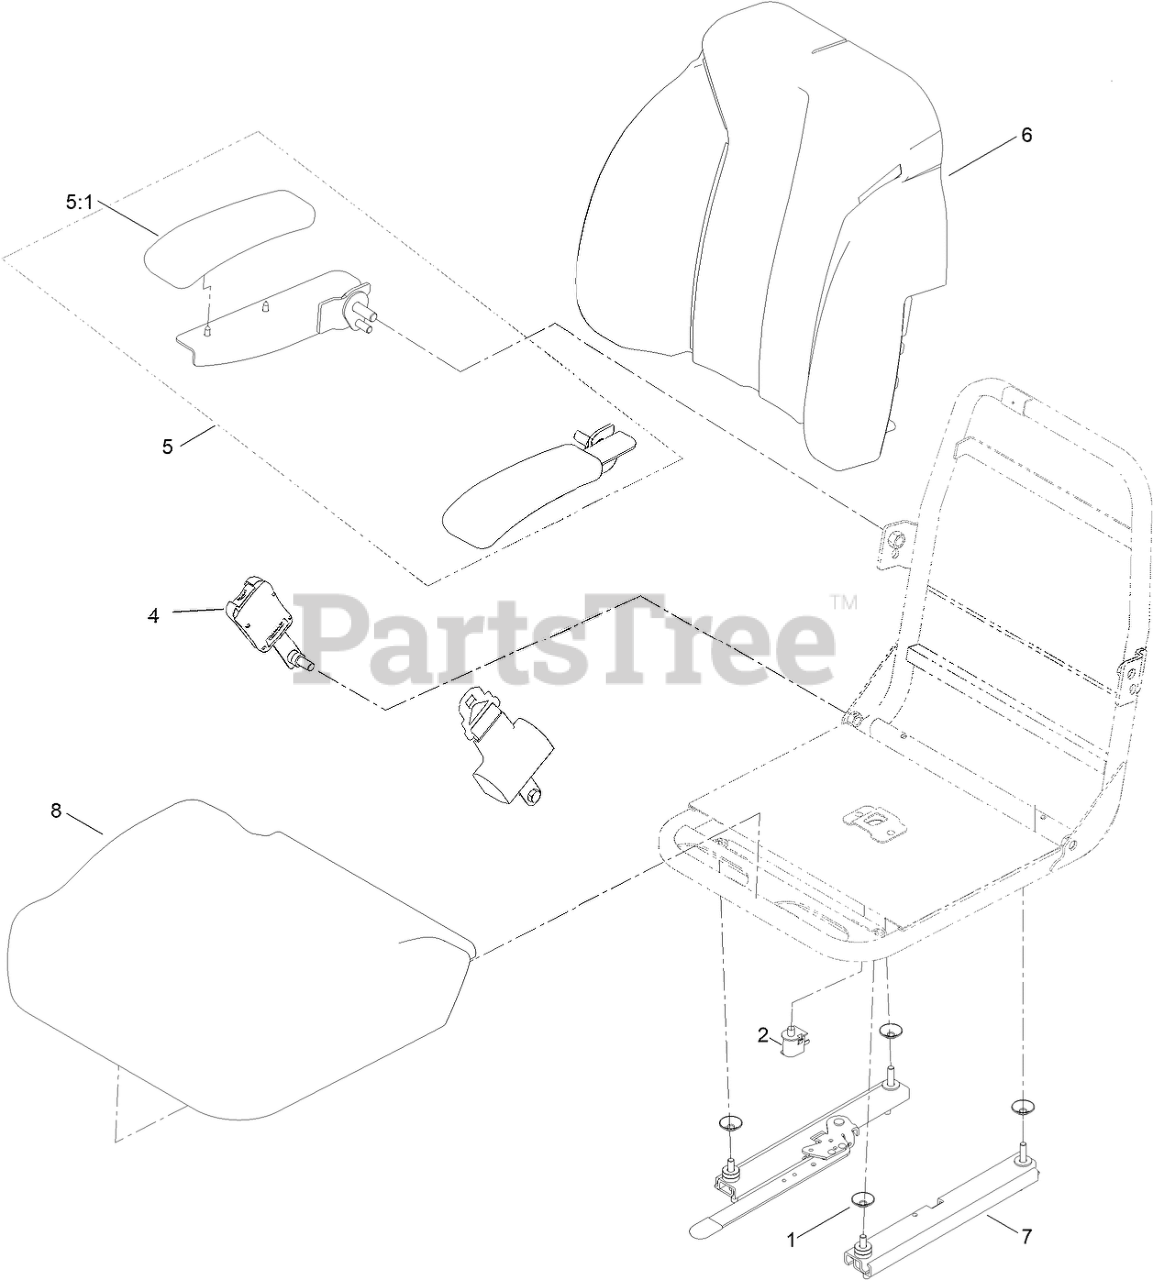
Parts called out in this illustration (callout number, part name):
1	SPACER-MOUNTING
2	SWITCH-BAIL
4	SEAT BELT KIT
5	ARMREST KIT
5:1	CUSHION-REST, ARM
6	COVER-BACK, SEAT
7	TRACK-SEAT
8	COVER-SEAT, BOTTOM
